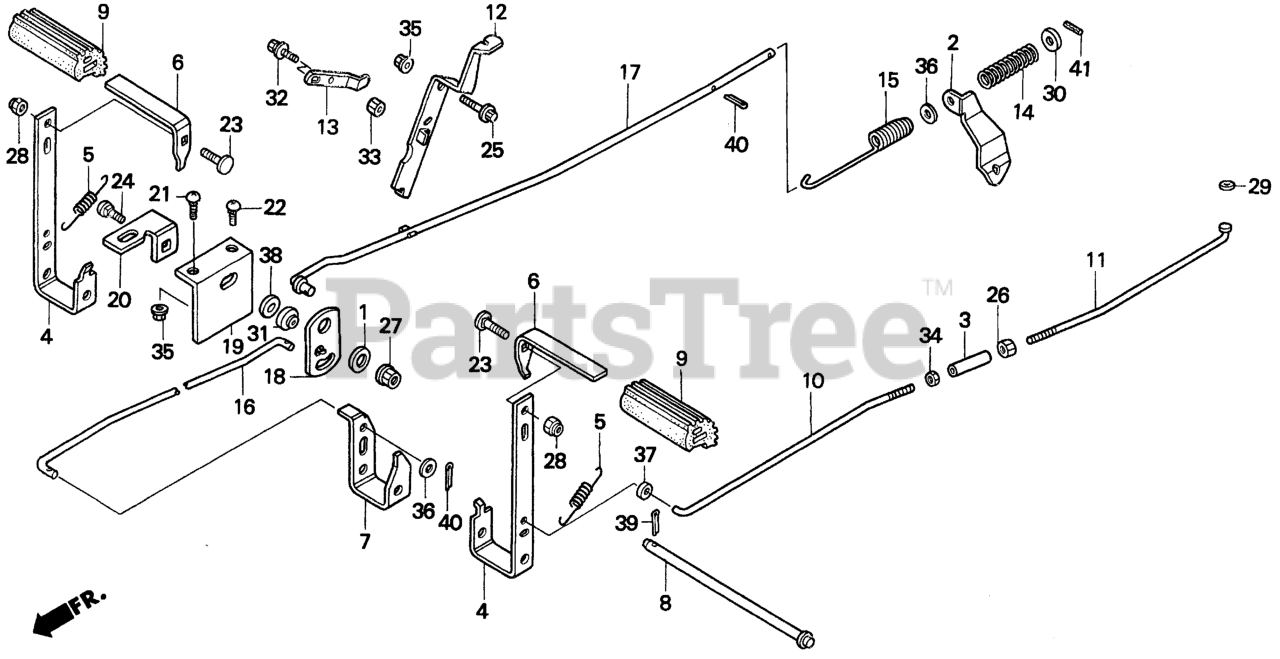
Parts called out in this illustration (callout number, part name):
1	WASHER (42X8.5)
2	ARM, RR. BRAKE
3	JOINT (8MM)
4	PEDAL, BRAKE/CLUTCH
5	SPRING, BRAKE PEDAL
6	BRACKET, BRAKE/CLUTCH
7	ARM, BRAKE
8	SHAFT, PEDAL
9	RUBBER, PEDAL
10	ROD A, CLUTCH
11	ROD B, CLUTCH
12	LEVER, PARKING BRAKE
13	SPRING, PARKING BRAKE LEVER
14	SPRING, BRAKE LOAD
15	SPRING, BRAKE DAMPER
16	ROD, RR. BRAKE
17	ROD B, RR. BRAKE
18	ARM, BRAKE MIDDLE
19	BRACKET, BRAKE MIDDLE
20	PLATE, BRAKE MIDDLE ARM
21	BOLT, SPECIAL (8X20)
22	BOLT, SPECIAL (9X15)
23	BOLT, SPECIAL (8X27)
24	BOLT, SPECIAL (8X37)
25	BOLT, ADJUSTING ARM
26	NUT, HEX. (8MM)
27	NUT, FLANGE (8MM)
28	NUT, FLANGE (8MM)
29	WASHER A, HANDLE HOLDER SETTING
30	WASHER, PLAIN (0.63)
31	COLLAR, TENSION ARM
32	BOLT-WASHER (5X12)
33	NUT, HEX. (5MM)
34	NUT, HEX. (8MM)
35	NUT, FLANGE (8MM)
36	WASHER, PLAIN (10MM)
37	WASHER, PLAIN (8MM)
38	WASHER, PLAIN (8MM)
39	PIN, SPLIT (3.0X25)
39	PIN, COTTER (3.0X45)
40	PIN, SPLIT (4.0X22)
41	PIN, SPRING (4X25)
